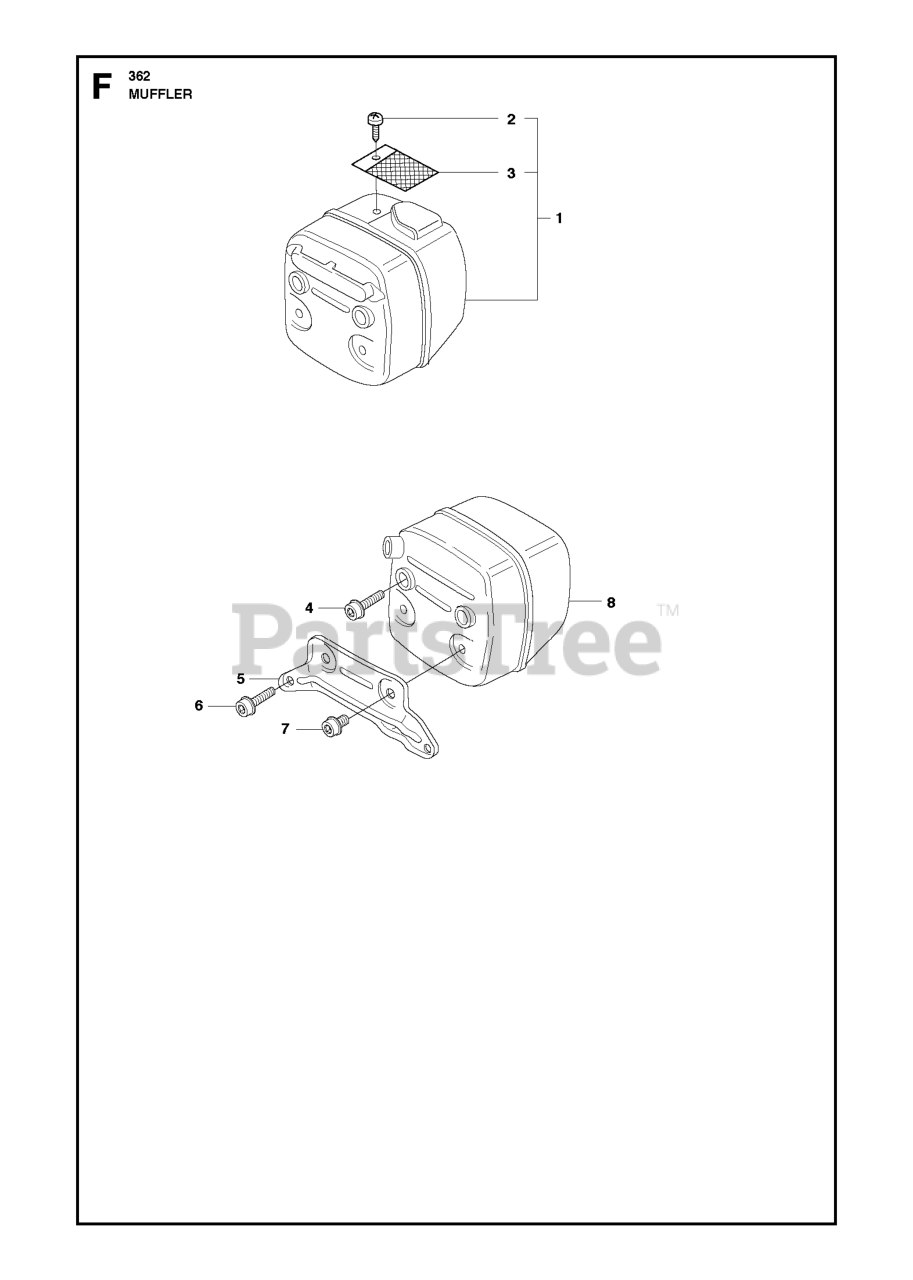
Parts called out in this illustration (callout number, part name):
1	MUFFLER
4	SCREW ITXSCM M6X20 T27 12.9 T
7	SCREW ITXSCFM M5X8 T27 10.9 Z
8	MUFFLER ASSY
